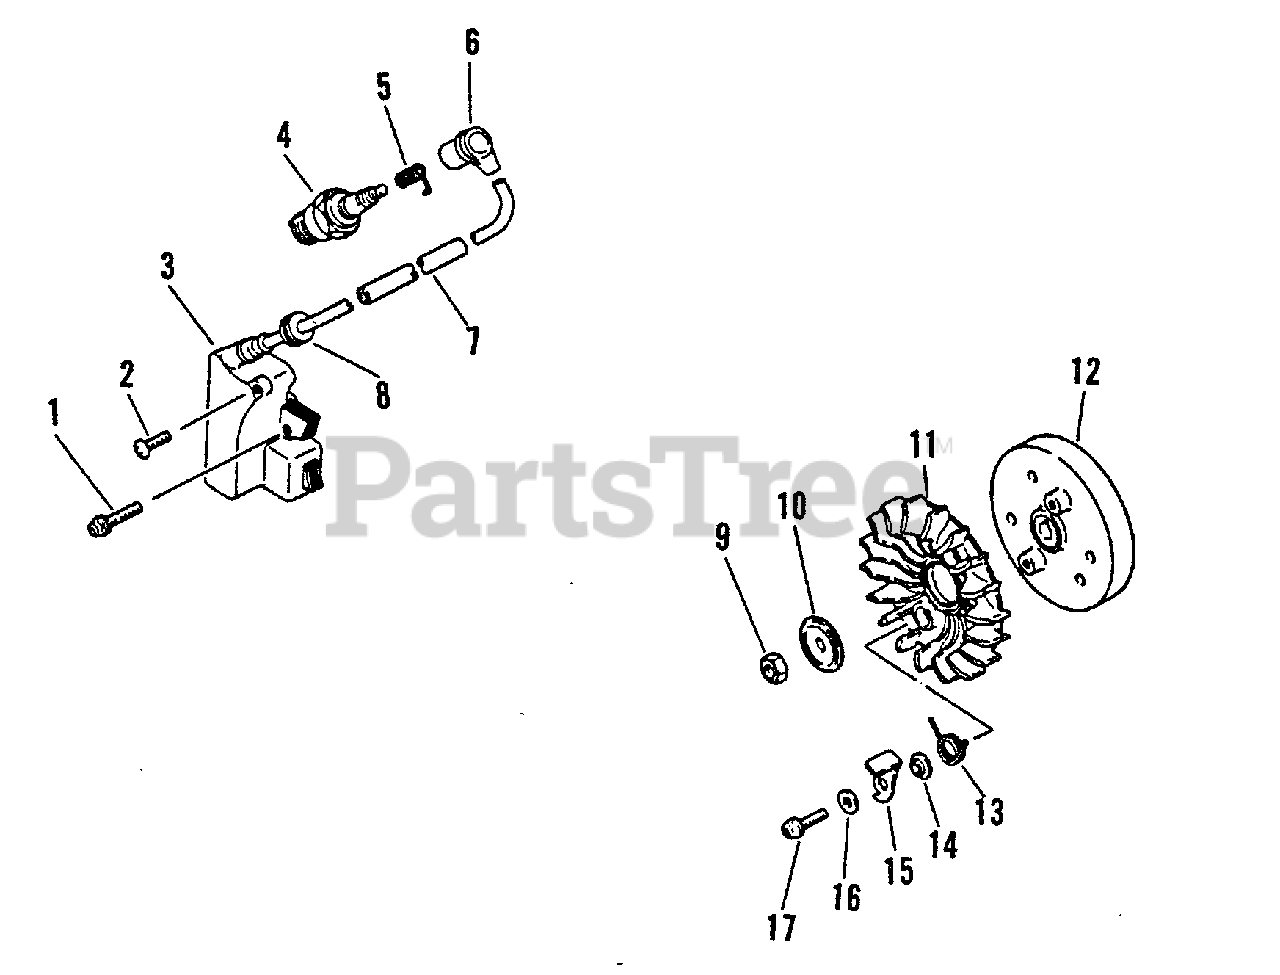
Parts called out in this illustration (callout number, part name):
1	SCREW - 4X20
2	SCREW - 4X8
3	COIL, IGNITION
4	SPARK PLUG -- BPM-7A
5	TERMINAL, SPARK PLUG CAP
6	CAP, SPARK PLUG
10	WASHER - CUP
11	FAN
12	FLYWHEEL
13	SPRING, RETURN
15	PAWL, STARTER
16	WASHER - 5
17	SCREW - 5X14
